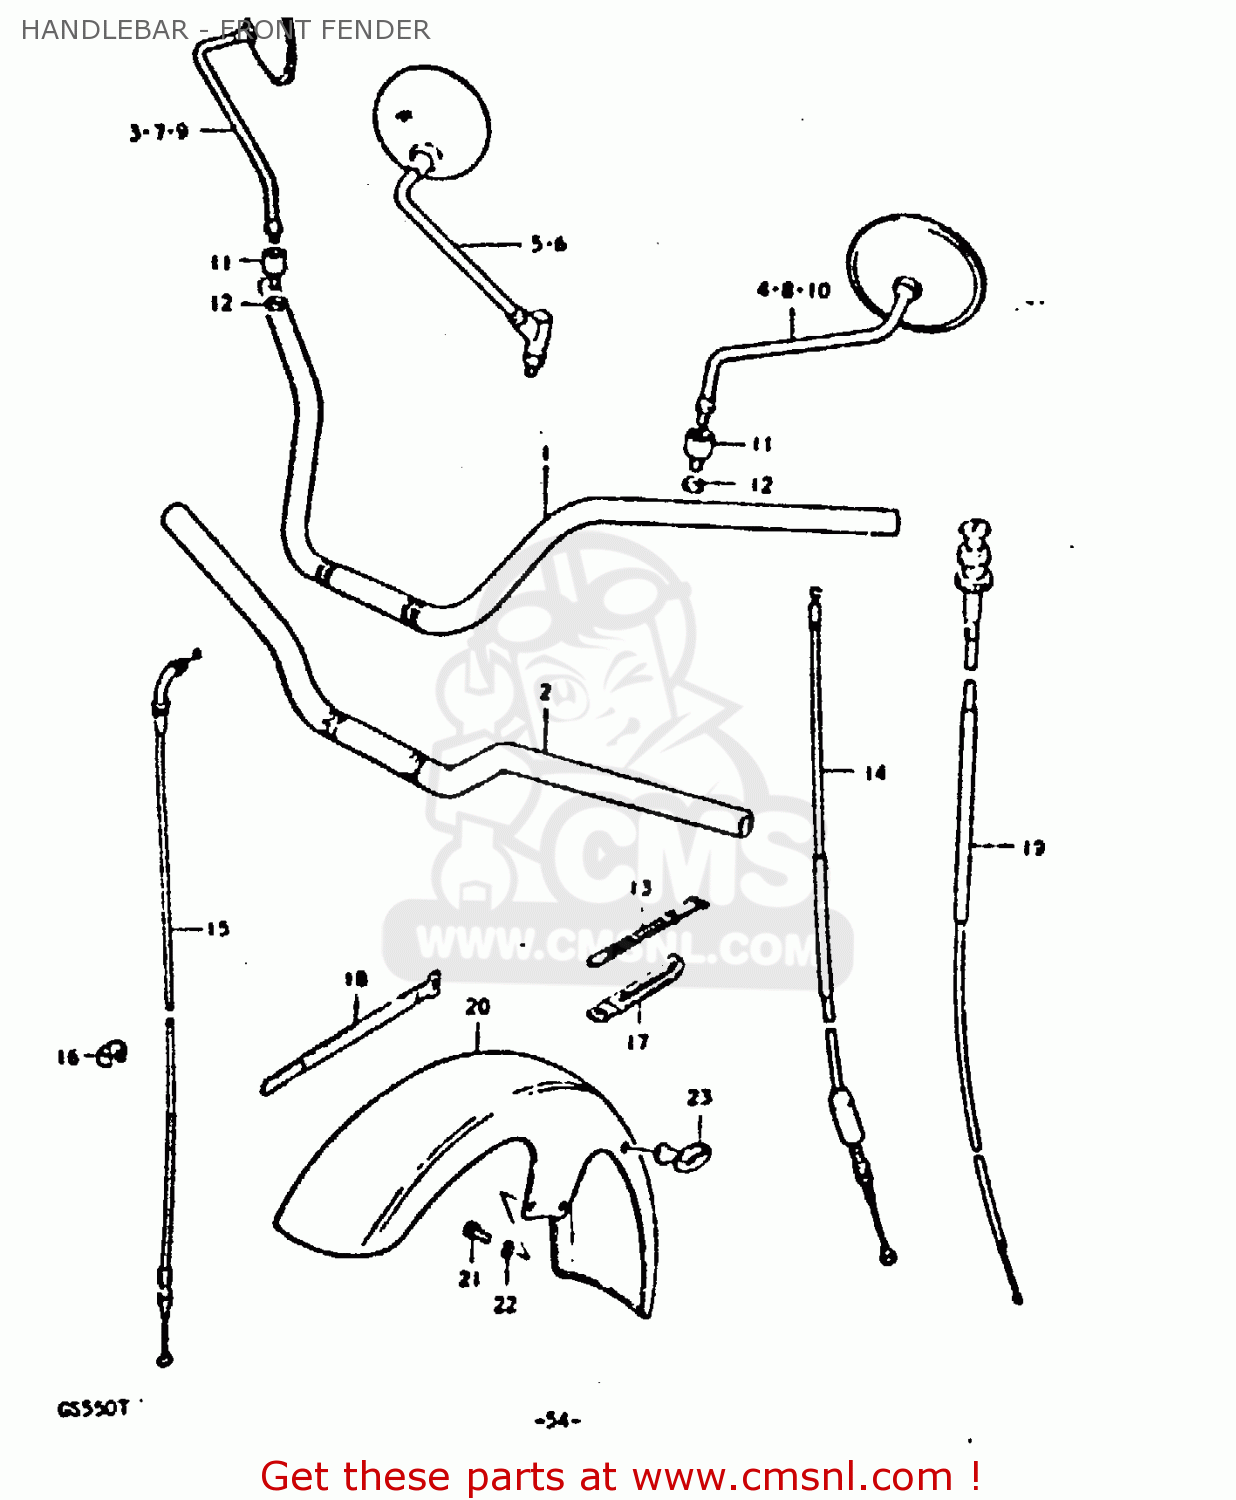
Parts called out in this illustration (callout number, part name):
1	HANDLEBAR
2	HANDLEBAR
3	MIRROR ASSEMBLY,REAR VIEW
4	MIRROR ASSEMBLY,REAR VIEW
5	MIRROR ASSY,RH
11	CUSHION,REAR VIEW MIRROR
12	NUT
13	CLAMP(L:120)
14	CABLE ASSY,CLUTCH
15	CABLE ASSEMBLY,THROTTLE
16	CLIP
17	CLAMP
18	CLAMP
19	CABLE ASSEMBLY,STARTER
20	FENDER ASSY,FR
21	BOLT
22	LOCK WASHER
23	GUIDE,CABLE
